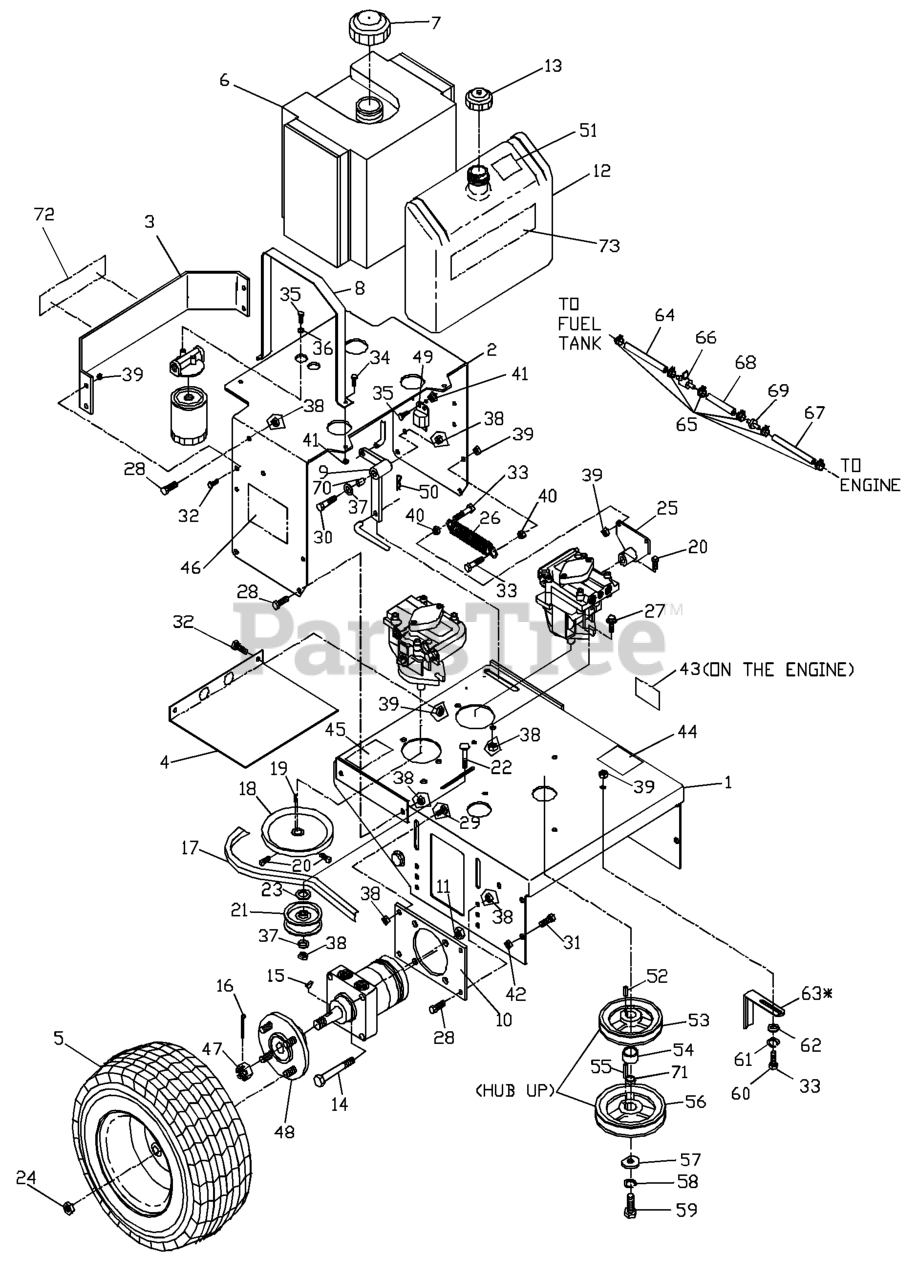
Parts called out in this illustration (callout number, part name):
1	REAR DECK W/DECALS
2	TANK SUPPORT, WLDMT
4	LOWER BELT SHIELD
5	WHEEL, COMPLETE
5	WHEEL
5	VALVE STEM TR-412
8	TANK STRAP
9	BELL CRANK
10	MOTOR MOUNT, 36
10	MOTOR MOUNT, 48
11	NUT 1/2-13 HEX NYLOC ZD
13	HYDRAULIC CAP
14	HCS 1/2C X 2 3/4
15	KEY, #808 WOODRUFF
16	COTTER PIN
17	TRANSMISSION BELT
19	KEY 5 MM SQ X 25 MM
20	SCREW 5/16C X 5/8 SQ HEAD
21	IDLER PULLEY
22	RHSNB 3/8C X 2
23	WASHER 1/2 FLAT
24	LUG NUT 1/2F
25	PUMP ARM WLDMT
26	SPRING-TRANS
27	4CS 3/8C X 1 SERRATED HEAD
28	HCS 3/8-16X1.GRD.5.ZD
29	RHSNB 3/8C X 1
30	HCS 3/8C X 2
31	HCS 7/16-14 X 1 GR 5 ZD
32	HCS 5/16C X 3/4
33	HCS 5/16C X 1 3/4
34	HCS 1/4 X 1
35	HCS 1/4C X 5/8
36	LOCKWASHER 1/4"
37	WASHER 3/8 FLAT
38	NUT 3/8C CENTERBLOCK
39	NUT 5/16C CENTERLOCK
39	(17 Kawasaki only)
40	NUT 5/16C WHIZ
41	NUT 1/4C CENTERLOCK
42	NUT 7/16C CENTERLOCK
43	DECAL, EXHAUST
44	DECAL, PROP. 65
45	DECAL, DANGER
46	DECAL, CROWN H
47	NUT 3/4-16 HEX SLTD GR5 ZD
48	HUB.WHEEL.ZTR
50	HAIRPIN #2
51	DECAL, HYDRAULIC FLUID
52	KEY 1/4 SQ X 3/4
55	KEY 1/4 SQ X 1 1/8
56	PULLEY, ENGINE
57	WASHER, CRANKSHAFT
58	WASHER 7/16 LOCK
59	HCS M10-1.5X35MM
59	HCS 7/16F X 1 1/2
60	HTB M8-1.125 X 25MM
60	HCS M8-1.25 X 30MM
61	WASHER.LOCK.HVY.HLCL.SPR.5/16
62	WASHER 5/16 FLAT
63	BELT GUIDE
63	BELT GUIDE - LONG
63	(36" MODEL)
63	BELT GUIDE, SHORT
64	FUEL LINE 16"
65	HOSE CLAMP
66	FUEL VALVE
67	GAS LINE 10"
68	GAS LINE 3 1/2"
68	FUEL LINE 14"
69	FUEL FILTER
70	BUSHING, SLEEVE
71	BUSHING, 10GA MACHINERY
72	DECAL, HUSQVARNA LOGO 9.25"
73	DECAL, WH3614
73	DECAL, WH4817
73	DECAL WH3615
